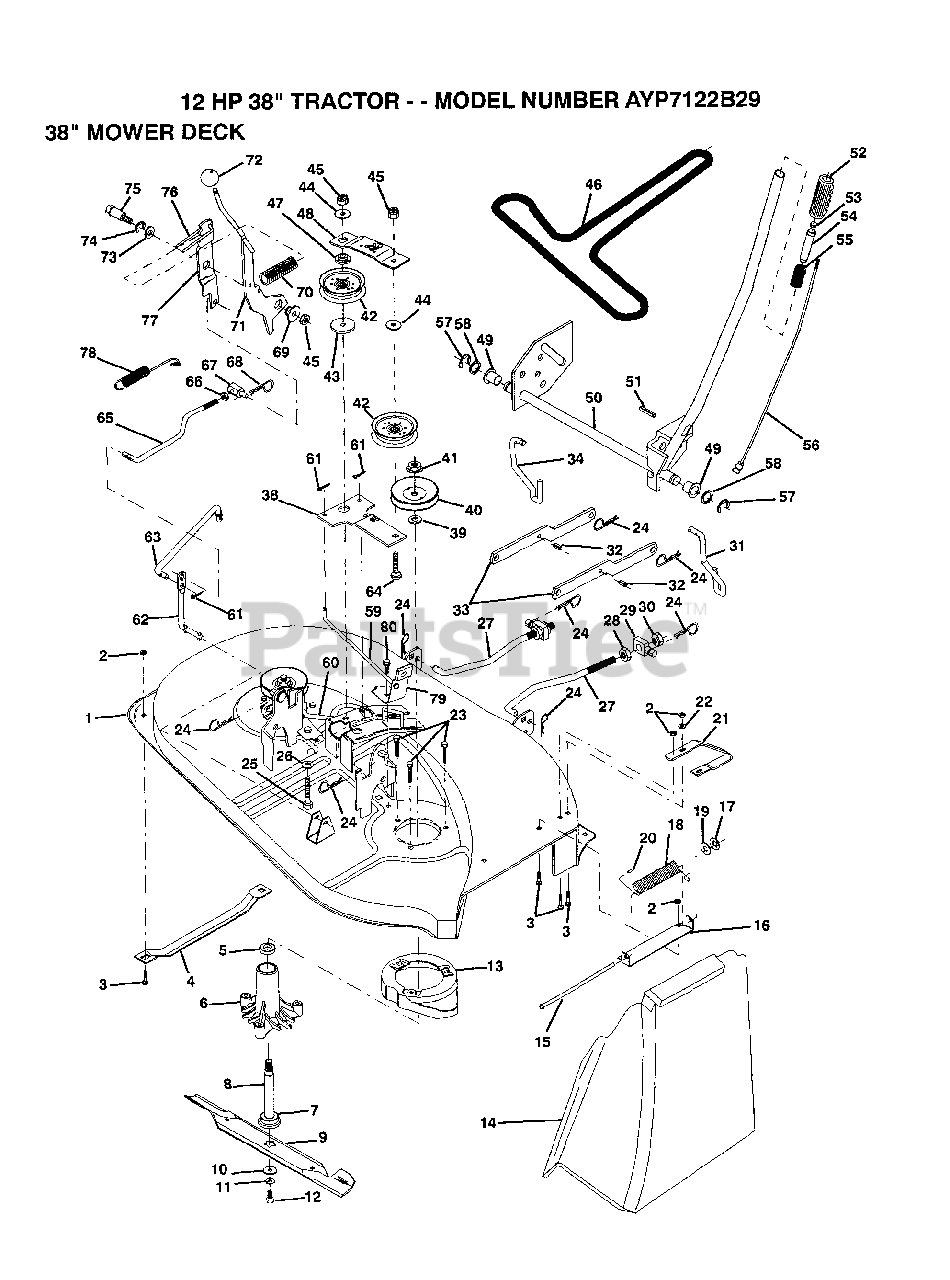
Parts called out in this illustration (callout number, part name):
3	BOLT
4	RUNNER-LH M
5	BEARING
6	HSG ASM MANDREL
7	BEARING.BALL
10	WASHER BLADE
12	BLADE BOLT
14	DEFLECTOR-SHLD T
15	ROD-HINGE T
17	NUT PUSH M
19	WASHER
20	CAP-SLEEVE LT
21	RUNNER RH
22	WASHER M
25	BOLT
26	WASHER GT
27	LINK.FRONT
28	NUT
29	TRUNION
30	NUT.LK.W/WSH.1/2.
31	LIFT LINK RH
32	"PIN,SPRING"
33	SUSP ARM ASM REAR
34	LINK LIFT LH
38	IDLER ARM ASSY
39	WASHER
42	FLAT IDLER PULLEY
43	SPACER RETAINER
44	WASHER GT
46	BELT-V.88.12.MW
47	RETAINER SPACER
48	IDLER ARM STIFF
49	NYLON BEARING
51	PIN-GROOVE LT
52	GRIP
58	WASHER
59	BRAKE ROD RH
60	BRAKE ROD LH
62	PIVOT ROD
63	CLUTCH ROD SECOND
64	BOLT
66	NUT
67	TRUNION
68	RETAINER M
69	BUSHING
72	KNOB T(3/8 HOLE)
73	WASHER
74	RING
75	SHOULDER BOLT
76	SPRING KEEPER
77	CLUTCH ARM SECOND
78	RETURN SPRING
79	BRAKE ASM
80	SCREW
